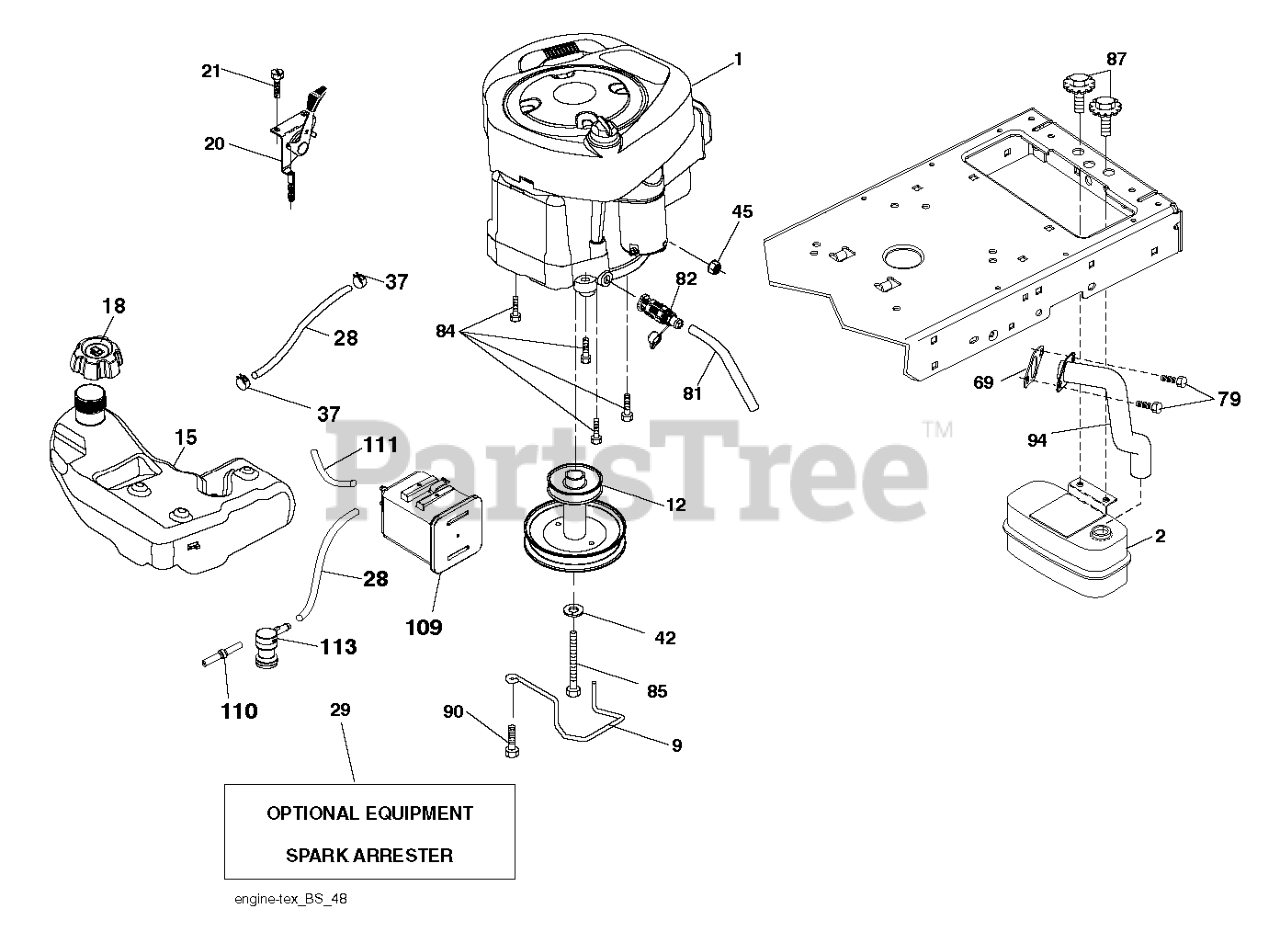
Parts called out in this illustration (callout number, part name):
2	MUFFLER.SINGLE.CYL.KOHL/B&S
9	KEEPER.BELT.ENGINE.4.2
12	PULLY ENGINE
15	TANK.ASM.FUEL.3GA.CARB
18	RP CAP ASM
20	CONTROL.TH/CK.COBRA.KO
21	SCREW.#10 X 0.750.BOS
28	LINE.FUEL.64"REAR.EMIS
29	KIT.SPARK ARRESTOR 794945 B&S
37	HOSE CLAMP
42	LOCKWASHER
45	NUT
69	REPL BY 532 27 22-93
79	SCREW.SOCKET HD.5/16-1
81	TUBE, DRAIN OIL ASM.
82	VALUE.OIL.DRAIN
84	SCREW.3/8-16
85	BOLT HEX 7/16-20X4-1/4"
87	BOLT.5/16-18UNCX3/4 W/SEMS.BLK
90	SCREW 3/8-16X1
94	EXHAUST.TUBE.B&S.
109	CANNISTER, CARBON
110	VALVE.ASM.ANTI-SLOSH
111	RP PURGE LINE
113	VALVE.SLANT.CARTRDG.90 DEG.TEX
